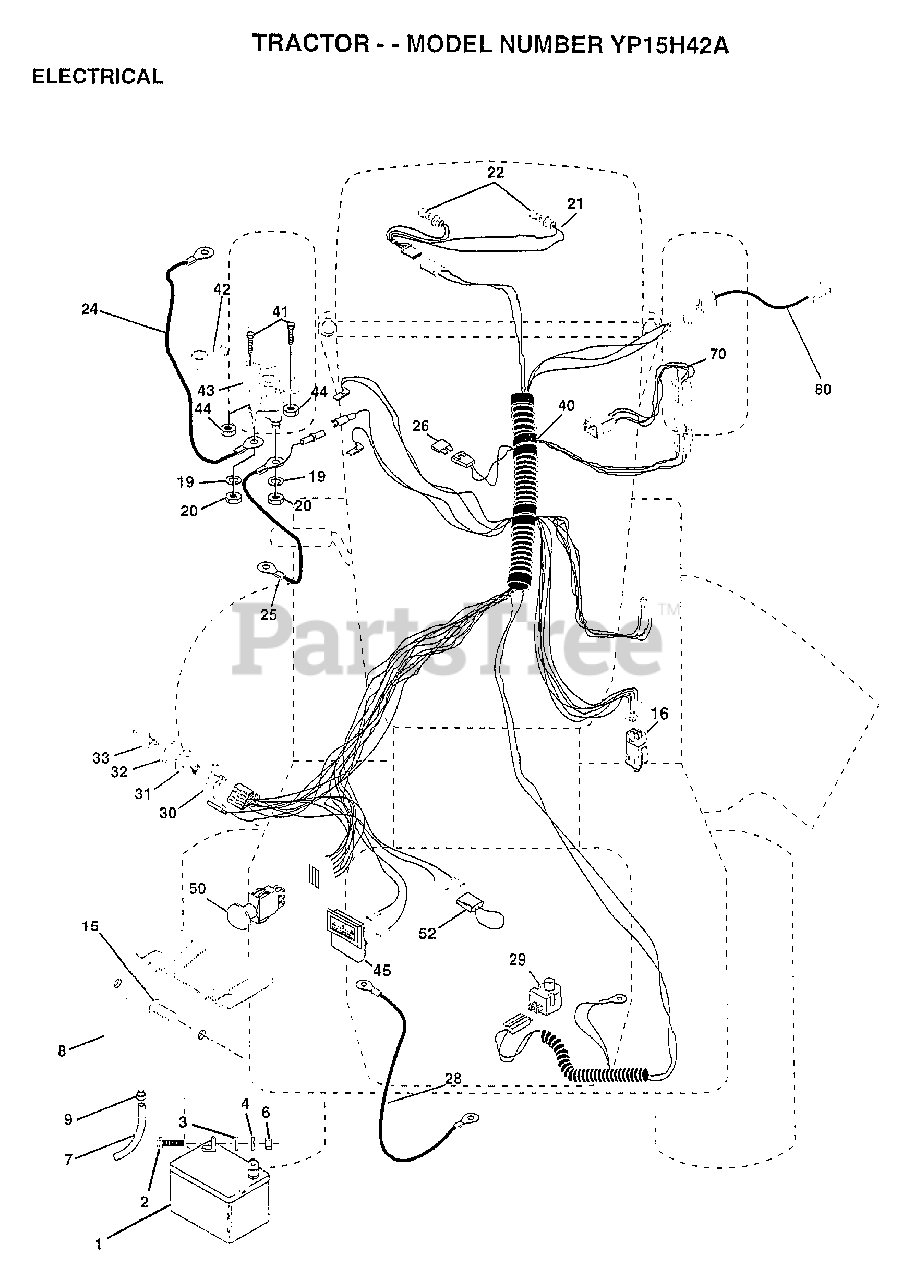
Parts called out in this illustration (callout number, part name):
2	BOLT LT
3	WASHER
4	LOCKWASHER
7	TUBE T
8	"CASE,BATTERY.MECH"
9	HOSE CLAMP T
15	FASTNER.SNAP-IN
16	SWITCH INTERLOCK
20	NUT
21	"HARNESS,LIGHT SOC"
22	HEADLAMP BULB
24	"CABLE T, BATTERY"
25	CABLE.BTRY.6GA.RD
26	FUSE HYT
28	CABLE T
29	SWITCH SEAT
30	SWITCH IGN 4POS
31	NUT IGNITION
32	COVER KEY SWITCH
33	KEY
40	HARNESS IGNITION
41	BOLT HXHD FIN
44	NUT HXKEP 1/4X20
50	PTO SWITCH.BLK
52	PROTECTION LOOP
70	HARNESS.ENG.B&S.
80	HARNESS.CLUT.EVX.
